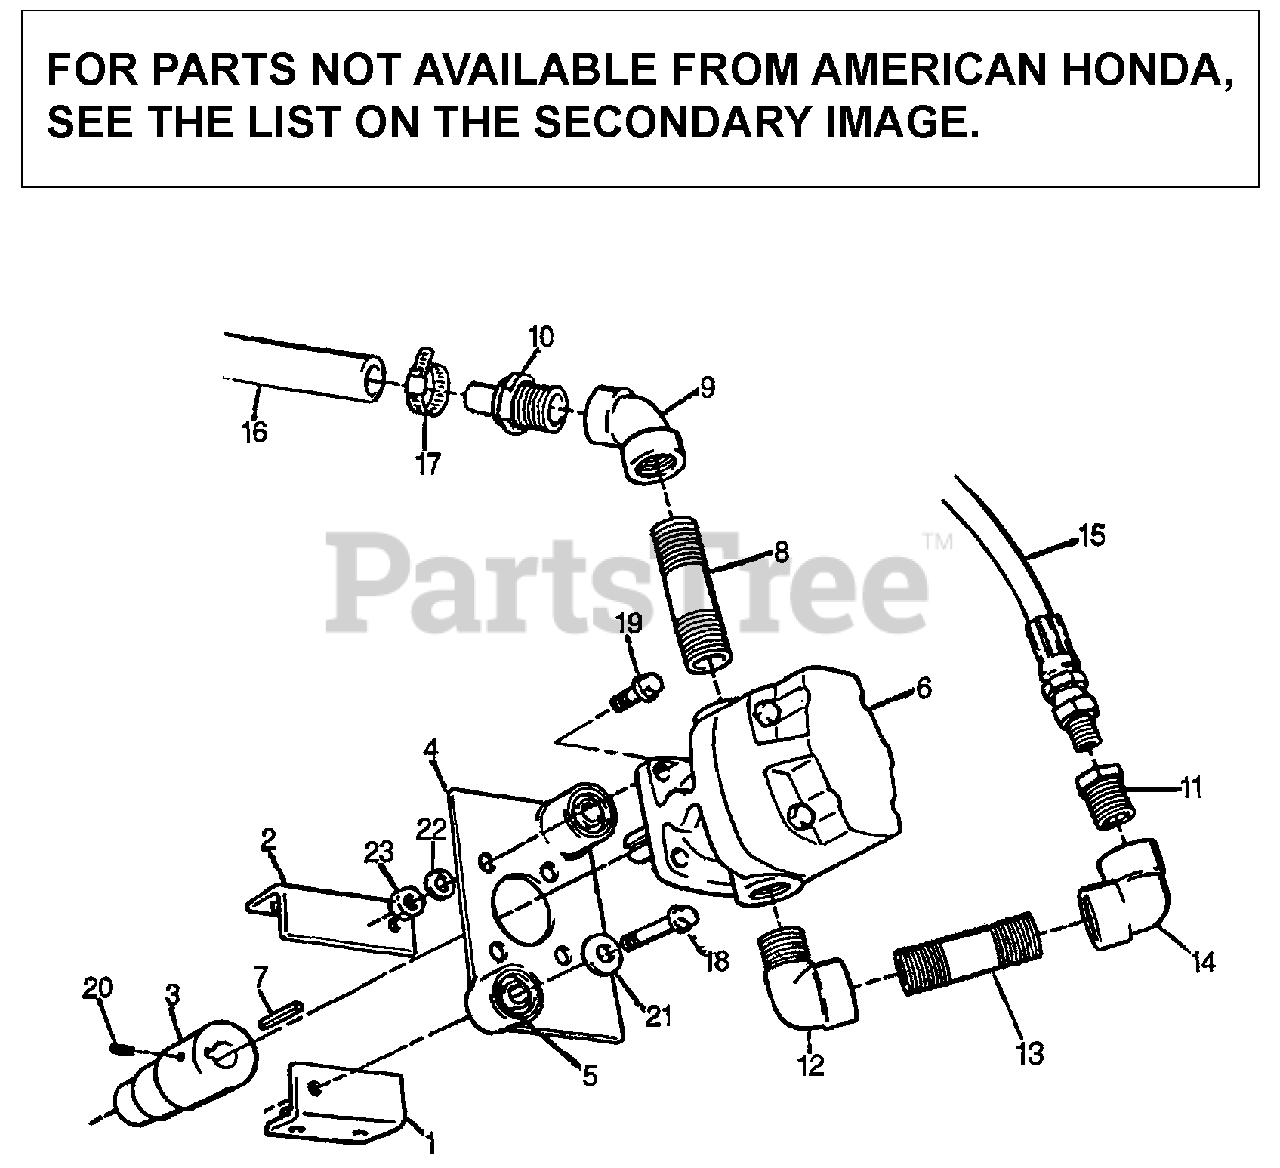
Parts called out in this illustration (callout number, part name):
5	BUSHING, RUBBER
6	PUMP (304)
10	PIPE END (1/2")
11	BUSHING, HEX. (1/2"-3/8")
15	HOSE, HYDRAULIC (3/8X60")
16	HOSE, SUCTION (3/4X48")
20	PUMP SEAL KIT
NI	PUMP SEAL KIT
